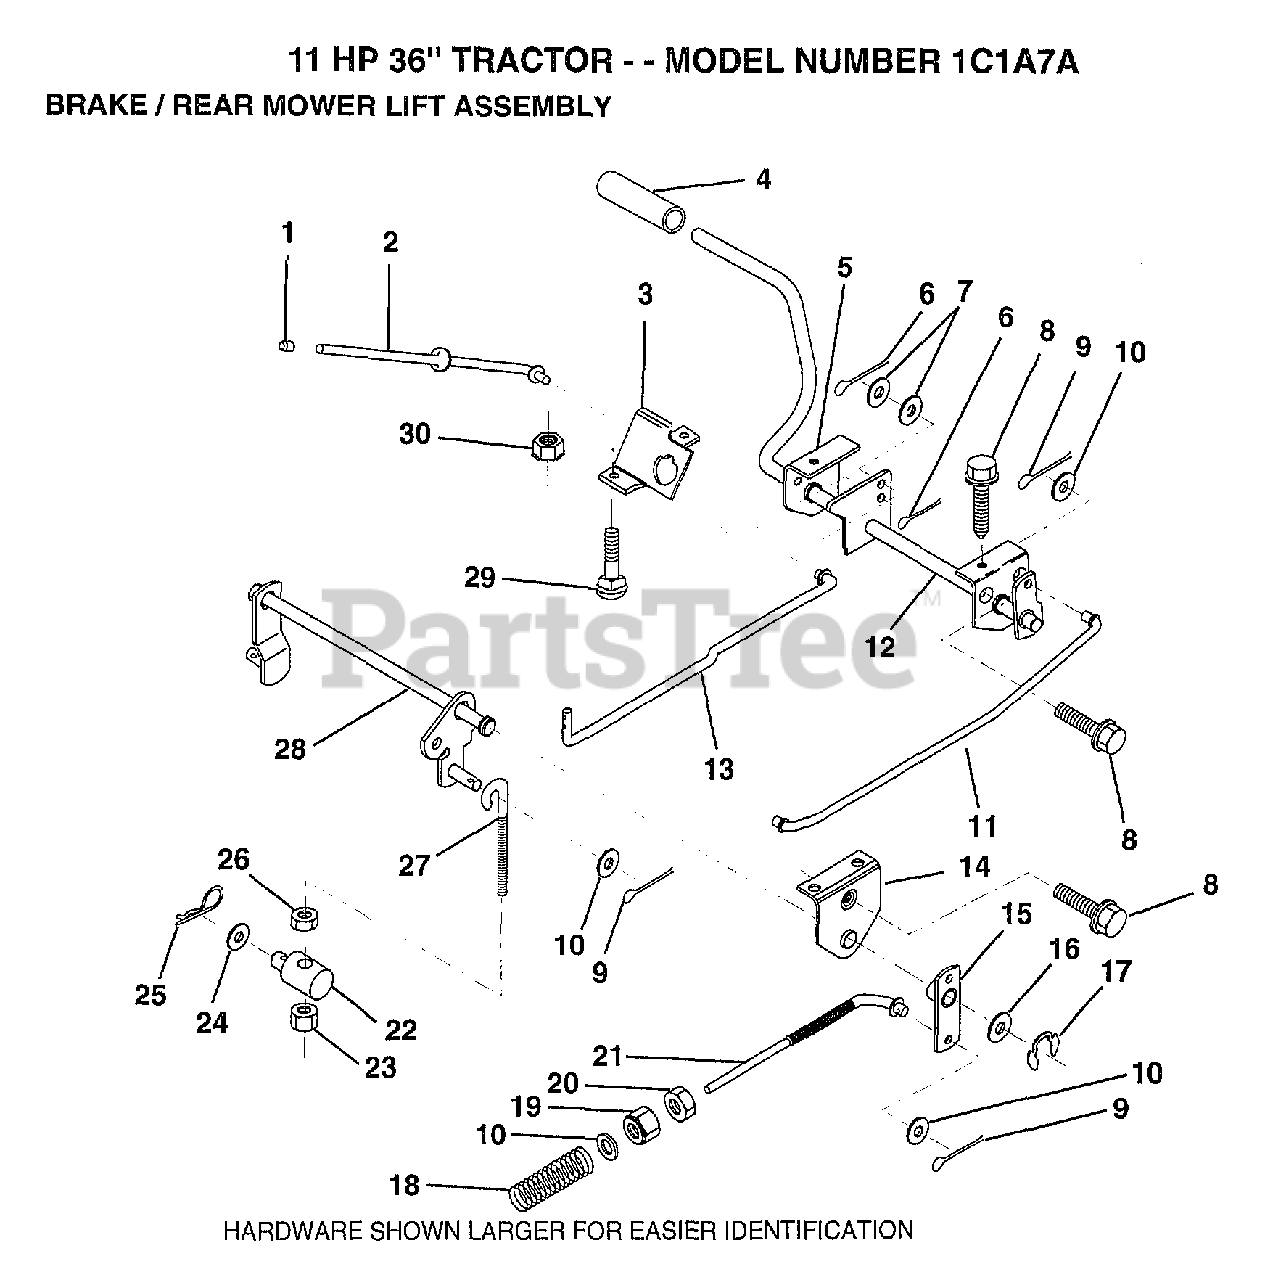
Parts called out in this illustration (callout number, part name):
1	PLUNGER CAP T
2	"ROD,PARK BRAKE"
3	"BRKT,PARK BRAKE"
4	FOOT PEDAL COVER
5	"BRKT,CLU PEDAL LH"
7	WASHER
8	SCREW LT
9	COTTER PIN
10	WASHER
11	"ROD,FRT BRAKE"
12	PEDAL ASM CL/BK36
13	"ROD,CLUTCH"
14	"BRKT,LIFT SHAFT"
15	PVT BRAKE ARM ASM
16	WASHER T
17	KLIP RING
18	SPRING ROD LT
19	NUT
20	NUT
23	NUT
24	WASHER
25	SPRING.RETAINER
26	LOCKNUT
27	"LINK, MOWER REAR"
28	LIFT ASM MOW REAR
